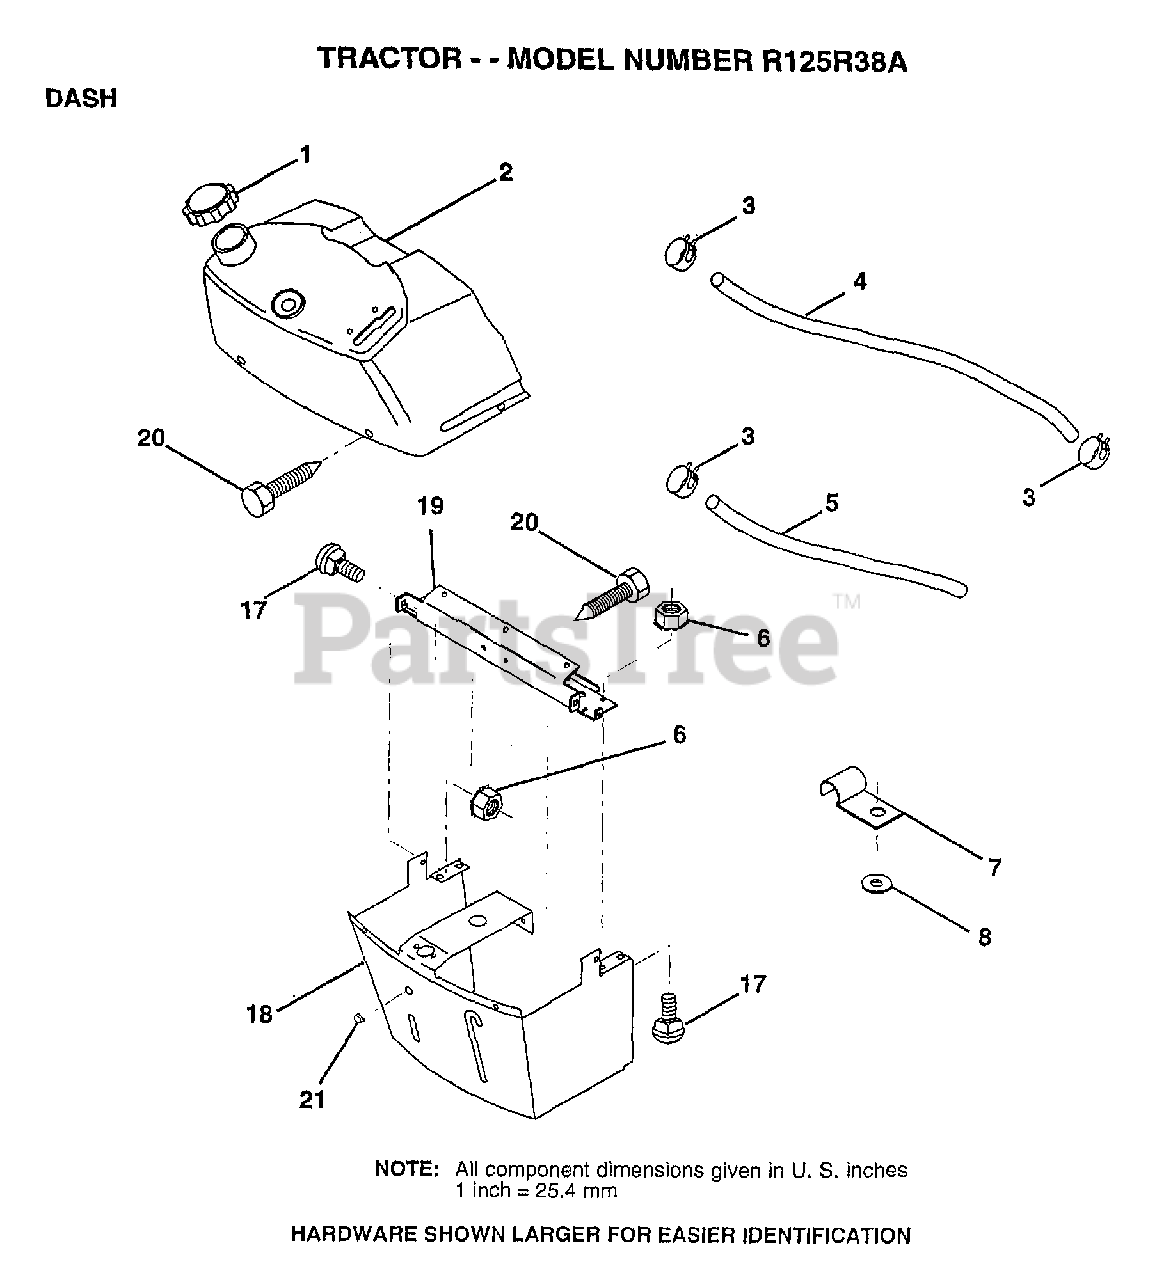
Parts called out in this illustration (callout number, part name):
1	CAP BLK FUEL LR
2	TANK.ASM.DASH.LR
3	HOSE CLAMP
5	FUEL LINE T
6	NUT HXKEP 1/4X20
7	CLIP T
8	WASHER PM
17	BOLT
18	SUPT ASM DASH
19	CROSS BRACE
20	SCREW.1/4-20X1/2
21	PLUG DOME
